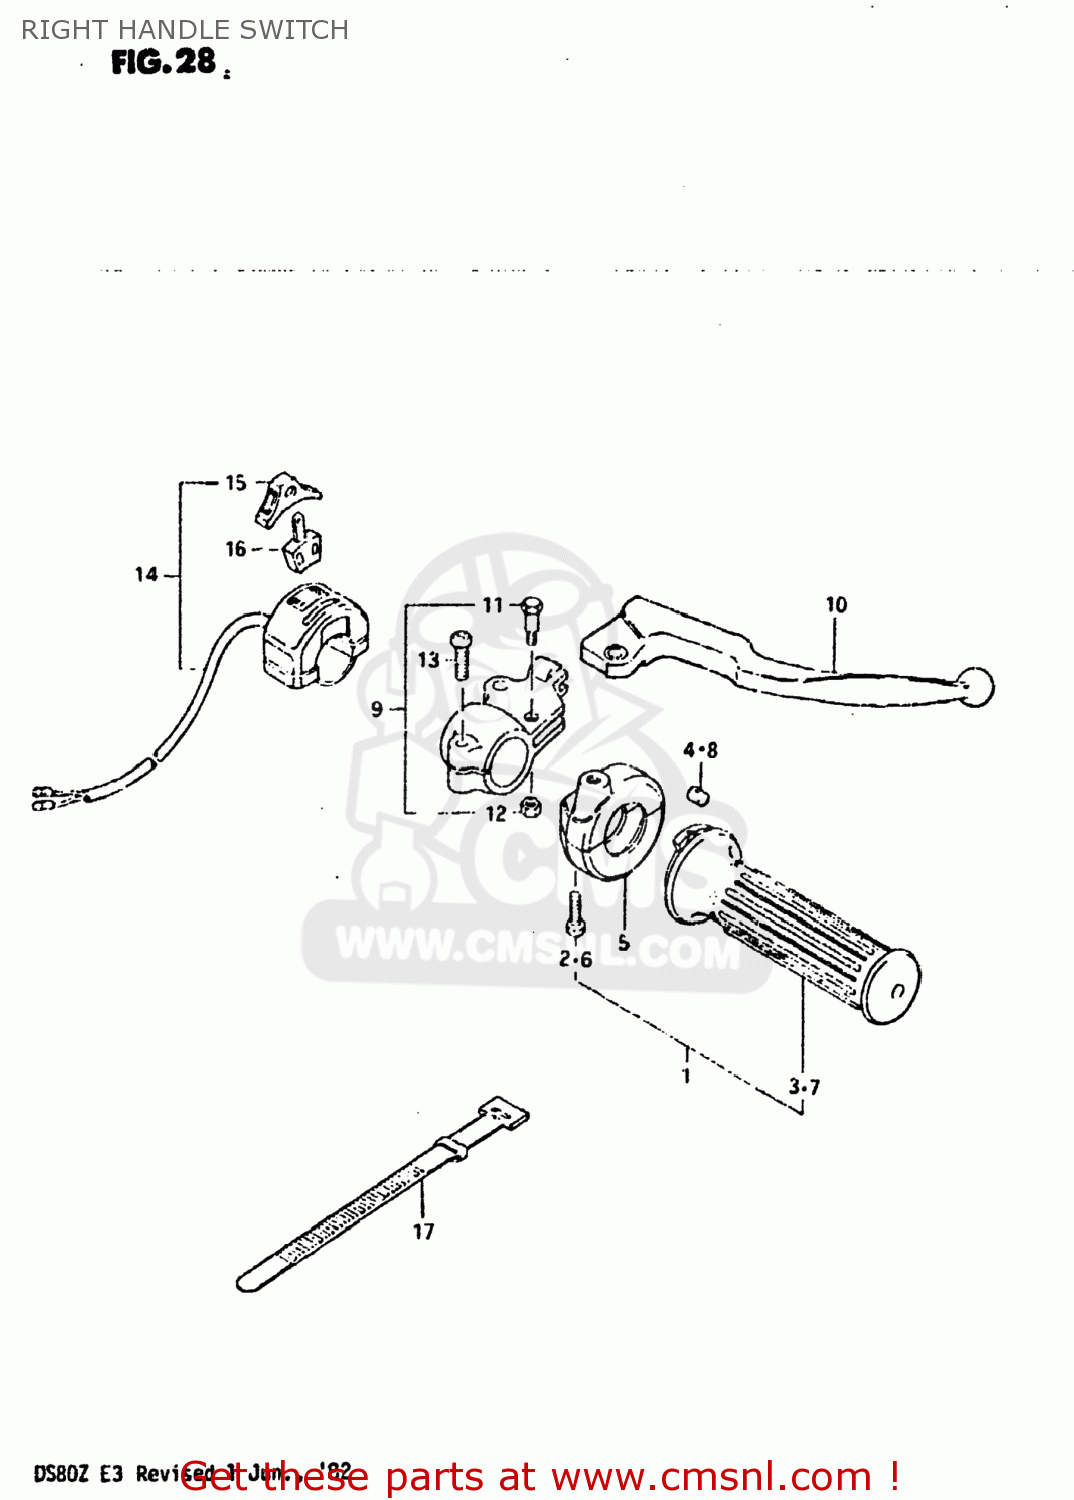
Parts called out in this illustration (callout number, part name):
1	CASE ASSEMBLY,THROTTLE
2	SCREW
3	GRIP,THROTTLE
4	PIECE,THROTTLE END
5	CASE ASSY,THROTTLE
6	SCREW
7	GRIP,THROTTLE
8	PIECE,THROTTLE END
9	LEVER ASSY,BRAKE
10	LEVER,BRAKE
11	BOLT,LEVER
12	NUT
13	SCREW
14	SWITCH ASSEMBLY,LIGHTING
15	KNOB,LIGHTING & DIMMER
16	BLOCK,LIGHTING/DIMMER
17	CLAMP(L:120)
